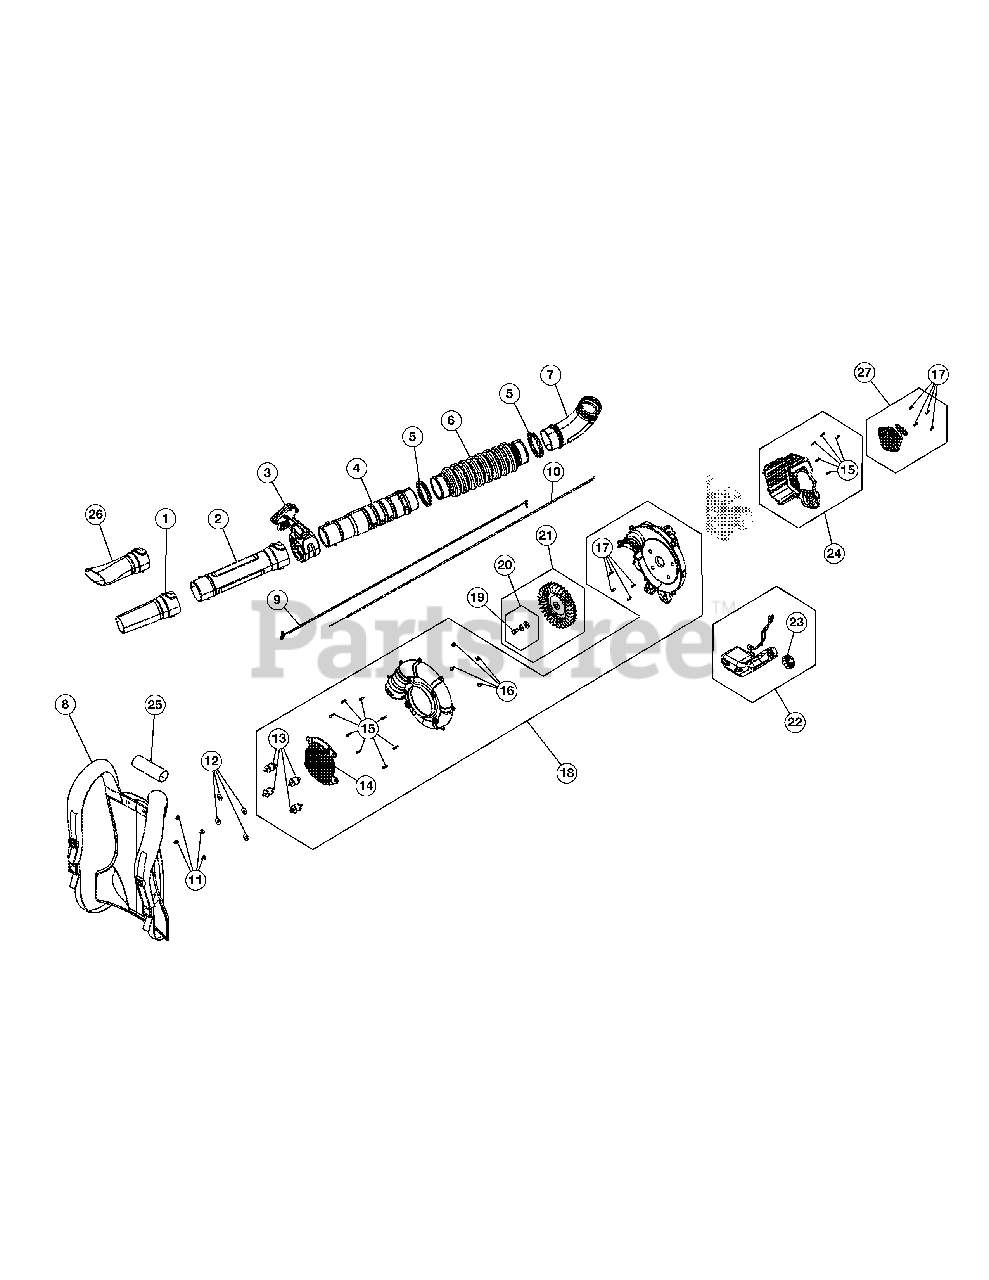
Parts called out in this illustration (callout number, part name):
1	Nozzle
2	Lower Blower Tube
3	Throttle Grip Assembly
4	Upper Blower Tube
6	Flex Tube
8	Harness
9	Lead Wire
10	Throttle Cable
11	Nut
12	Washer
13	Insulator Mount
14	Intake Cover
16	Nut
17	Screw
18	Impeller Housing Assembly (Incl. Ref No. 13-17)
20	Impeller Hardware (Incl. Ref No. 19)
21	Impeller (Incl. Ref No. 19 & 20)
22	Fuel Tank Assembly (Incl. Ref No. 23)
23	Fuel Cap
24	Housing Assembly (Incl. Ref No. 15)
26	Flare Nozzle
27	Starter Assembly (Incl. Ref No. 17)
